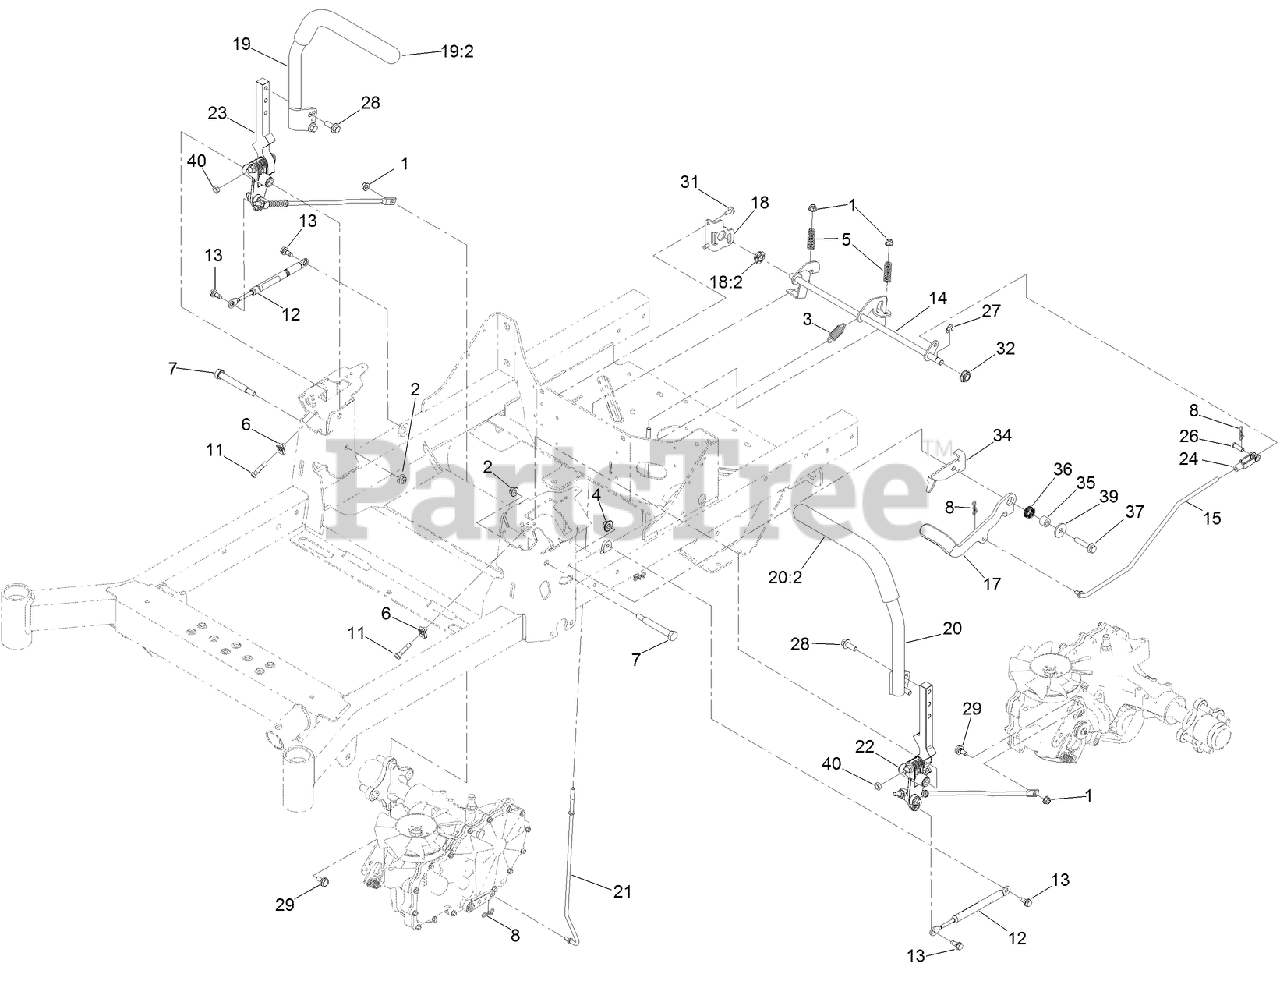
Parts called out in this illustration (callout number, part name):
1	NUT-HF, NI
2	NUT-HF, NI
3	SPRING-EXTENSION
4	NUT-FLANGE, NI
5	SPRING-COMPRESSION
7	BOLT-PIVOT
8	PIN-COTTER, LOCKING
11	SCREW-HSBH
12	DAMPER
13	SCREW-SHOULDER
14	SHAFT-BRAKE
15	LINKAGE-BRAKE, UPPER
17	LEVER-BRAKE (WITH GRIP)
18	BRACKET-BRAKE
18:2	BEARING-SPHERICAL
19	RH CONTROL HANDLE ASM
20	LH CONTROL HANDLE ASM
21	LINKAGE-BRAKE, LOWER
22	LH MOTION CONTROL ASM
23	RH MOTION CONTROL ASM
24	YOKE-ADJUSTABLE
26	PIN-CLEVIS
27	RING-RETAINING, EXTERNAL
28	SCREW-HHF
29	BOLT-SHOULDER
31	SCREW-TORX
32	BEARING-SPHERICAL
34	BRACKET-BRAKE
35	BUSHING
36	SPRING-WAVE
37	SCREW-HHF
39	WASHER
40	NUT-JAM
